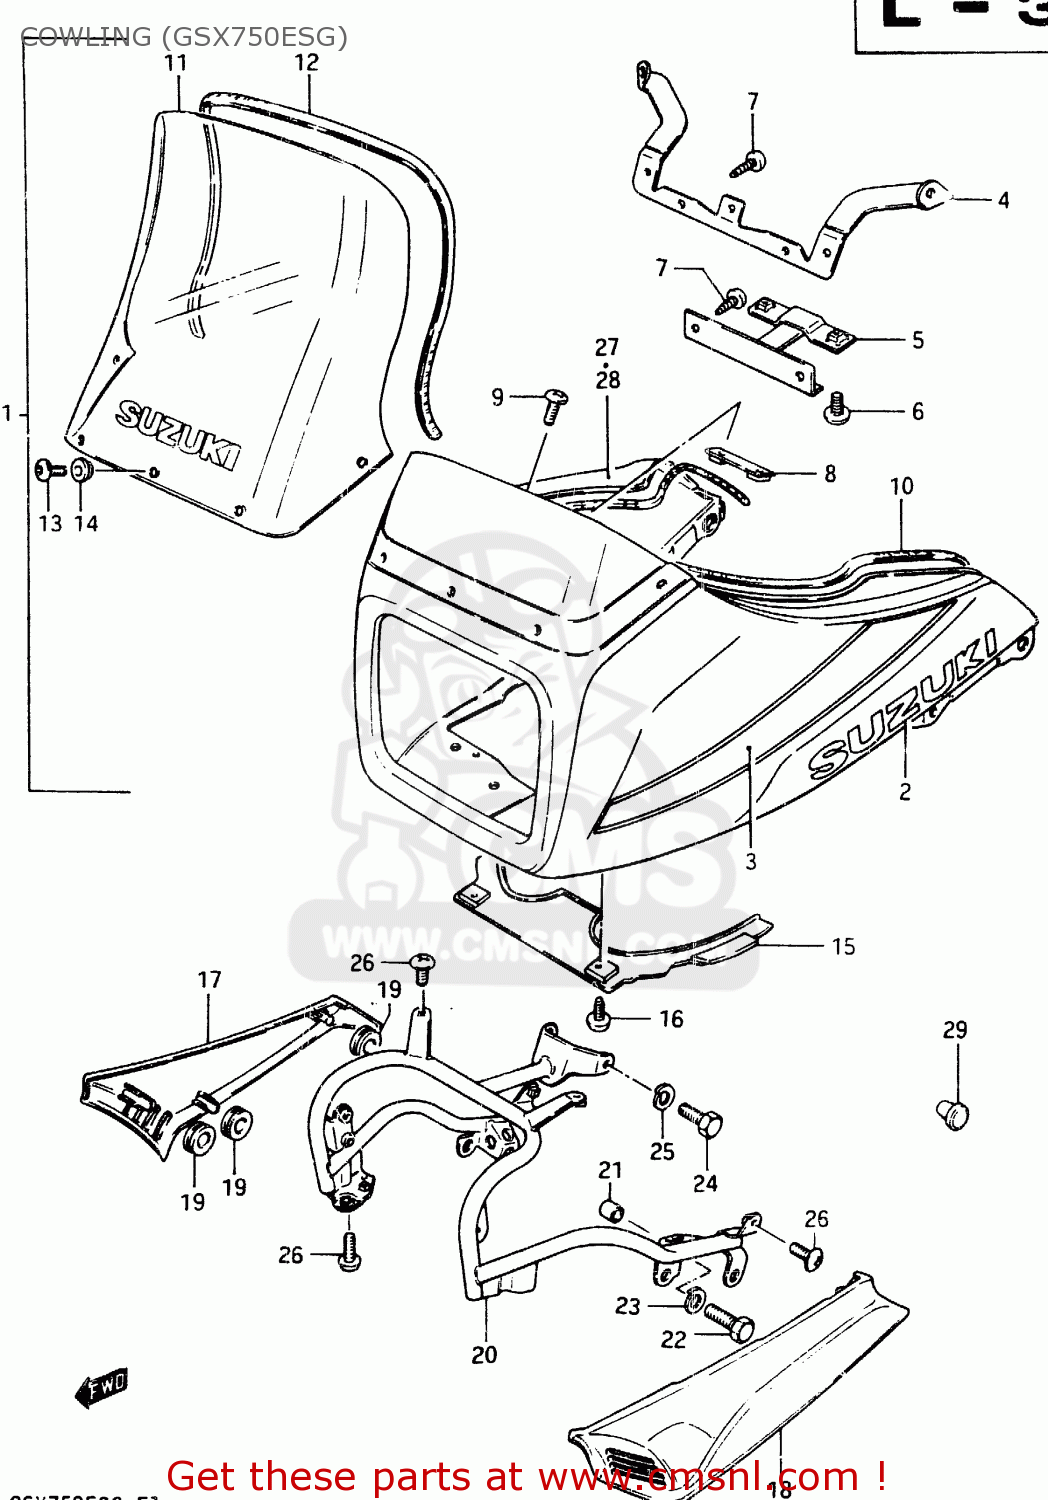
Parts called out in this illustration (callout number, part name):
1	COWLING ASSY (BLUE/RED)
2	EMBLEM, SIDE
3	TAPE SET
4	BRACE,COWLING,UPPER
5	BRACE,COWLING,LOWER
6	SCREW
7	SCREW
8	BRACE
9	SCREW
10	MOLDING,FUEL TANK
11	WINDOW
12	MOLDING
13	SCREW
14	CUSHION
15	COVER,COWLING,LOWER
16	SCREW
17	COVER COWL.RH
18	COVER COWL.LH
19	CUSHION
20	BRACE,COWLING
21	SPACER,COWLING
22	BOLT
23	WASHER,LOCK,8.
24	BOLT
25	WASHER,LOCK,8.
26	SCREW 6X12
27	TAPE,RIGHT
28	TAPE,LEFT
29	PLUG
